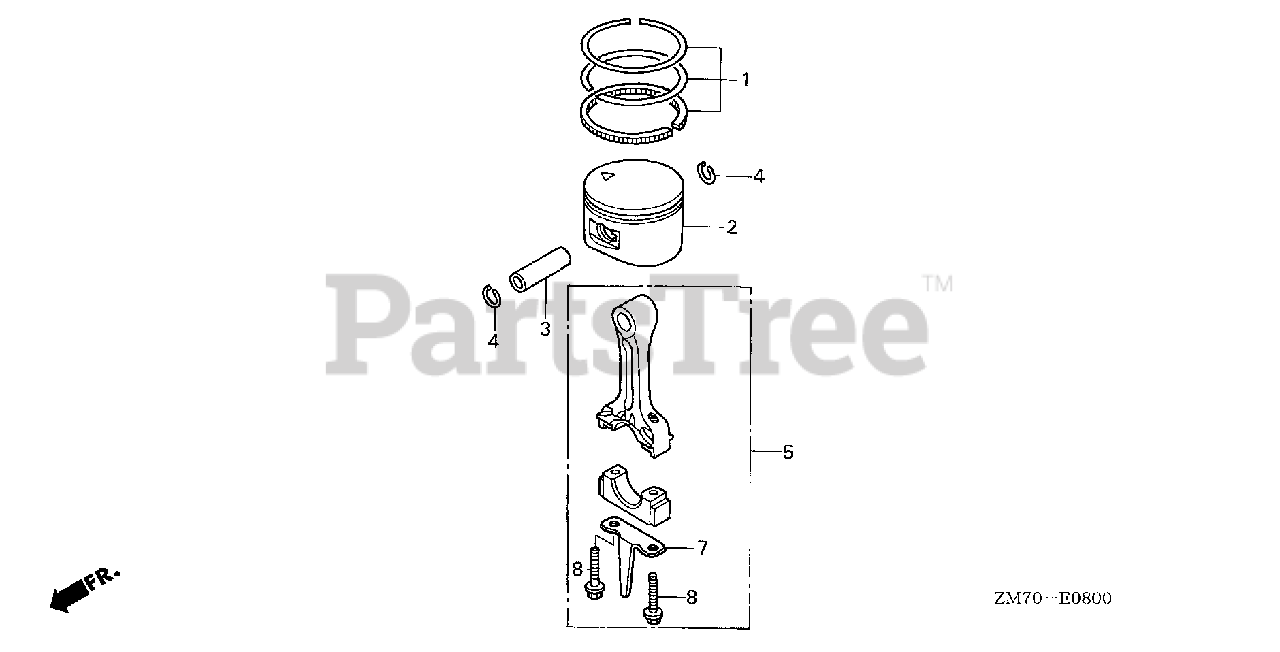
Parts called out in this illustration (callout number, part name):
1	RING SET, PISTON (STD)
2	PISTON (STD)
3	PIN, PISTON
4	CLIP, PISTON PIN (10MM)
5	ROD ASSY., CONNECTING
7	DIPPER, CONNECTING ROD
8	BOLT, CONNECTING ROD
